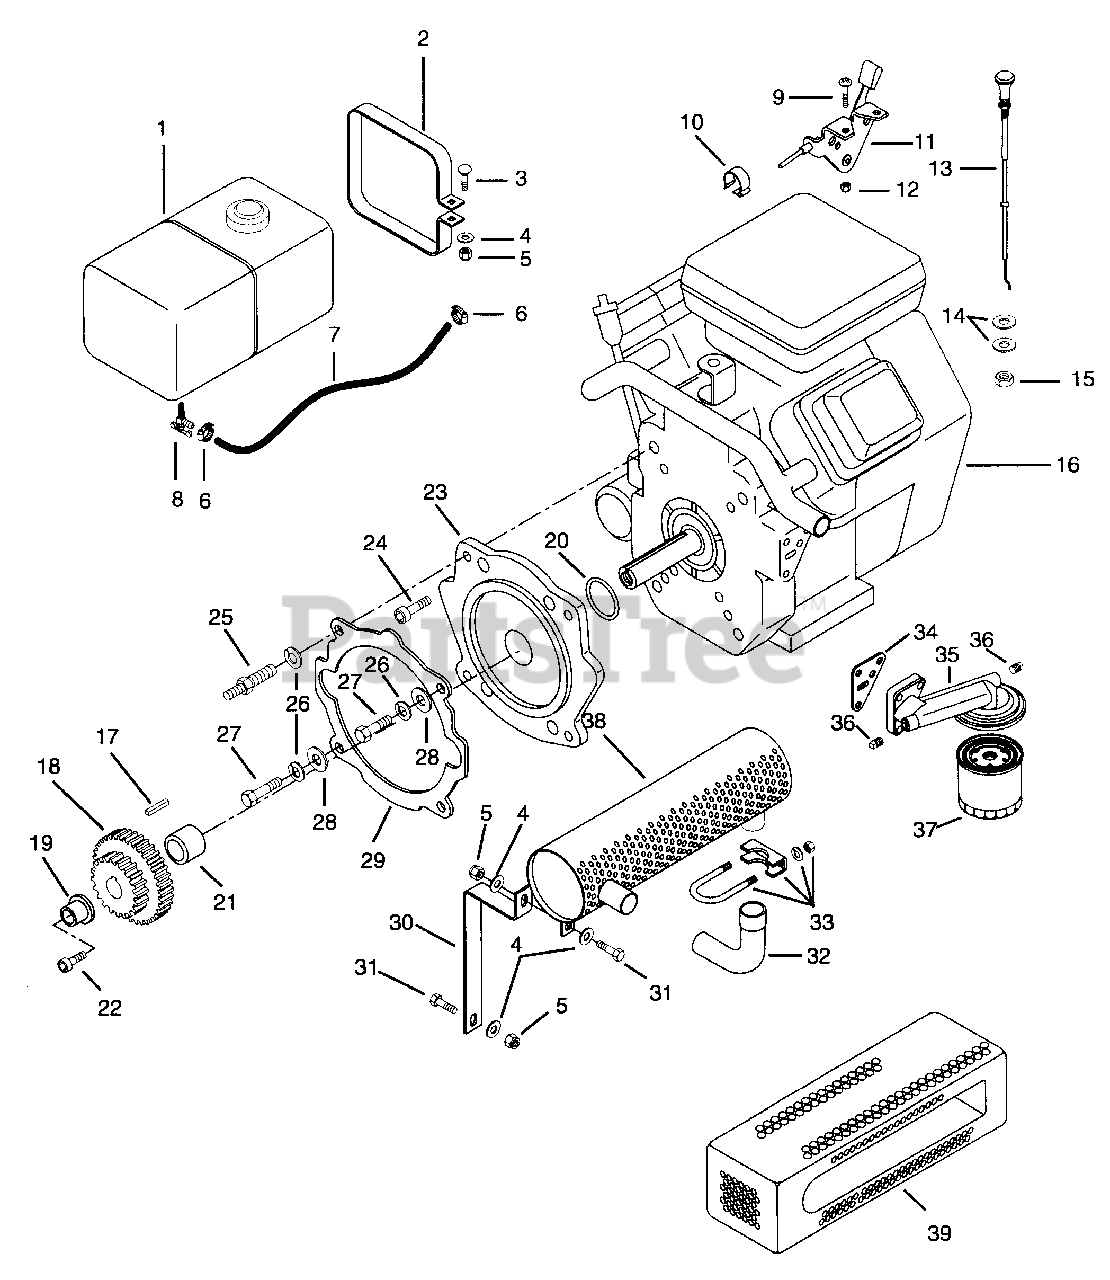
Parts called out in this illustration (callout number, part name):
1	Tank, Fuel, w/Cap, Black, 2-Wheel
2	Strap, Fuel Tank
3	Bolt-Round Head Square Neck .25-20 x 1.75
4	Washer-Flat-Steel .281 x .620 x .065
5	Nut-Locking-Center .250-20 Grade 2
6	Hose Clamp
7	Gas Line-Bulk
8	Valve & Strainer
9	Screw-Machine 10-24 x .50
11	Control, Choke Plated
12	Nut-Locking Nylon 10-24
13	Lever, Choke Control 8 HP
14	Washer-Flat-Steel .406 x .812 x .065
15	Nut-Jam .375-24
16	Engine, 16 HP B & S
17	Key-Square .248 x 1.0 x .248
18	Gear, B & S Engine
19	Pilot, Gear
20	O-Ring 1.850 x 2.270 x .210
21	Spacer 1.05 x 1.31 x 1.54
22	Screw-Machine .38-24 x 1.00
23	Adapter, B & S Engine
24	Screw-Socket Head .44-14 x 1.00
25	Stud
26	Washer-Lock .438 x .133
27	Bolt-Hex .44-14 x 1.50
28	Washer-Flat-Steel .459 x .938 x .065
29	Gasket, Chassis to Adapter
30	Bracket, Exhaust
31	Bolt-Hex .25-20 x 1.00 Grade 5
32	Elbow
33	Clamp-Muffler 1.25
34	Gasket, Oil Filter Adapter
35	Oil Filter Manifold
36	Plug-Pipe 1/16-27
37	Filter, Oil (114)
37	FIlter, Oil (305)
38	Muffler, 16 HP
39	Muffler Guard
